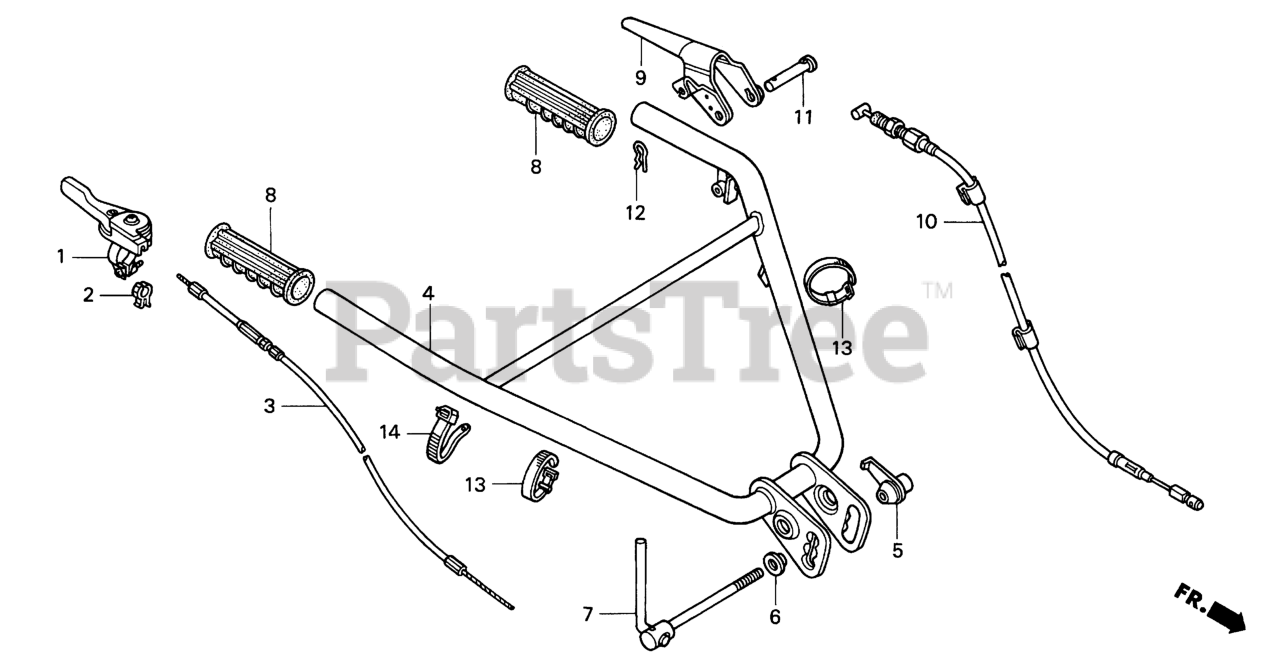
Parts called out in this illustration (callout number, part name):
1	LEVER ASSY., THROTTLE (RESIN MOLDED LEVER)
2	CLIP, THROTTLE (RESIN MOLDED CLIP)
3	CABLE, THROTTLE
4	PIPE, HANDLE
5	NUT, HANDLE LOCK
6	NUT, SPECIAL
7	LEVER, HANDLE ADJUSTING
8	GRIP, HANDLE
9	LEVER, CLUTCH
10	CABLE, MAIN CLUTCH
11	PIN, CLUTCH LEVER
12	PIN, LOCK (8MM)
13	BAND, CABLE (120MM) (BLACK)
14	BAND, SUCTION HOSE (BLACK)
